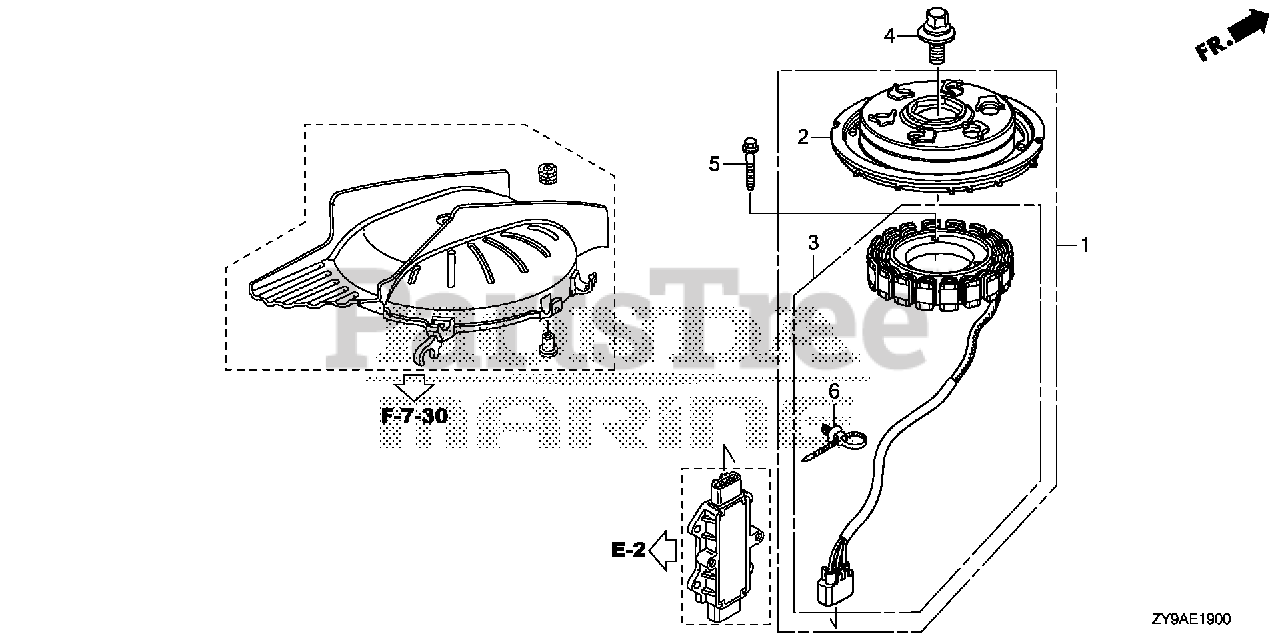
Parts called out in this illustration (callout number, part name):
1	ALTERNATOR ASSY.
4	BOLT-WASHER (14X36)
5	BOLT, FLANGE (6X32) (CT200)
6	CLIP, HARNESS BAND (96.9MM) (NATURAL)
